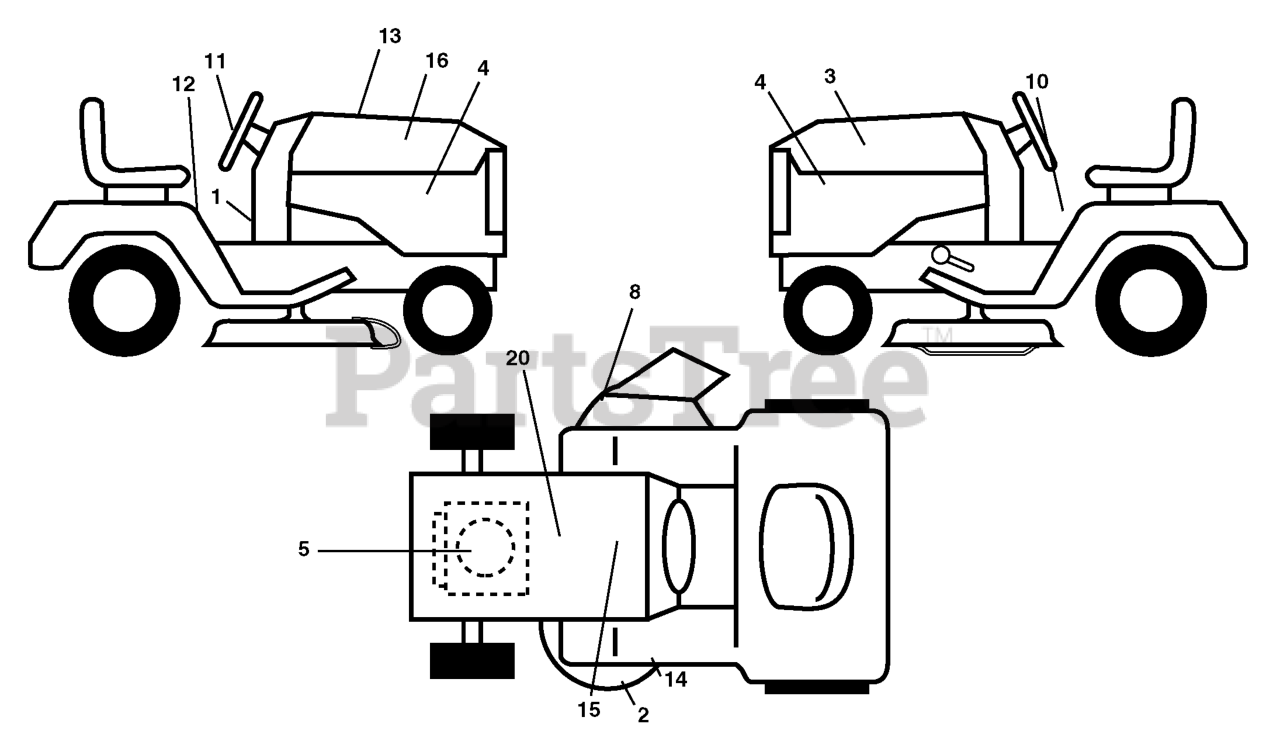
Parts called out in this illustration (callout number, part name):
2	DECAL, MOWER HEAVY DUTY
3	DECAL, HOOD LH
4	DECAL, PANEL YTH2448
5	DECAL.ENG.BS.24HP
8	DECAL.WARN.KEEP.HAND.AWAY
10	DECAL FENDER DANGER
11	DECAL.STEERING.HUSQ.BLUE
13	DECAL HOOD CUST. RESP.
14	DECAL V-BELT SCHEMATIC
15	DECAL. HD. RPL. HUSQ
16	DECAL, HOOD RH
20	DECAL BTRY SYMBOLS
